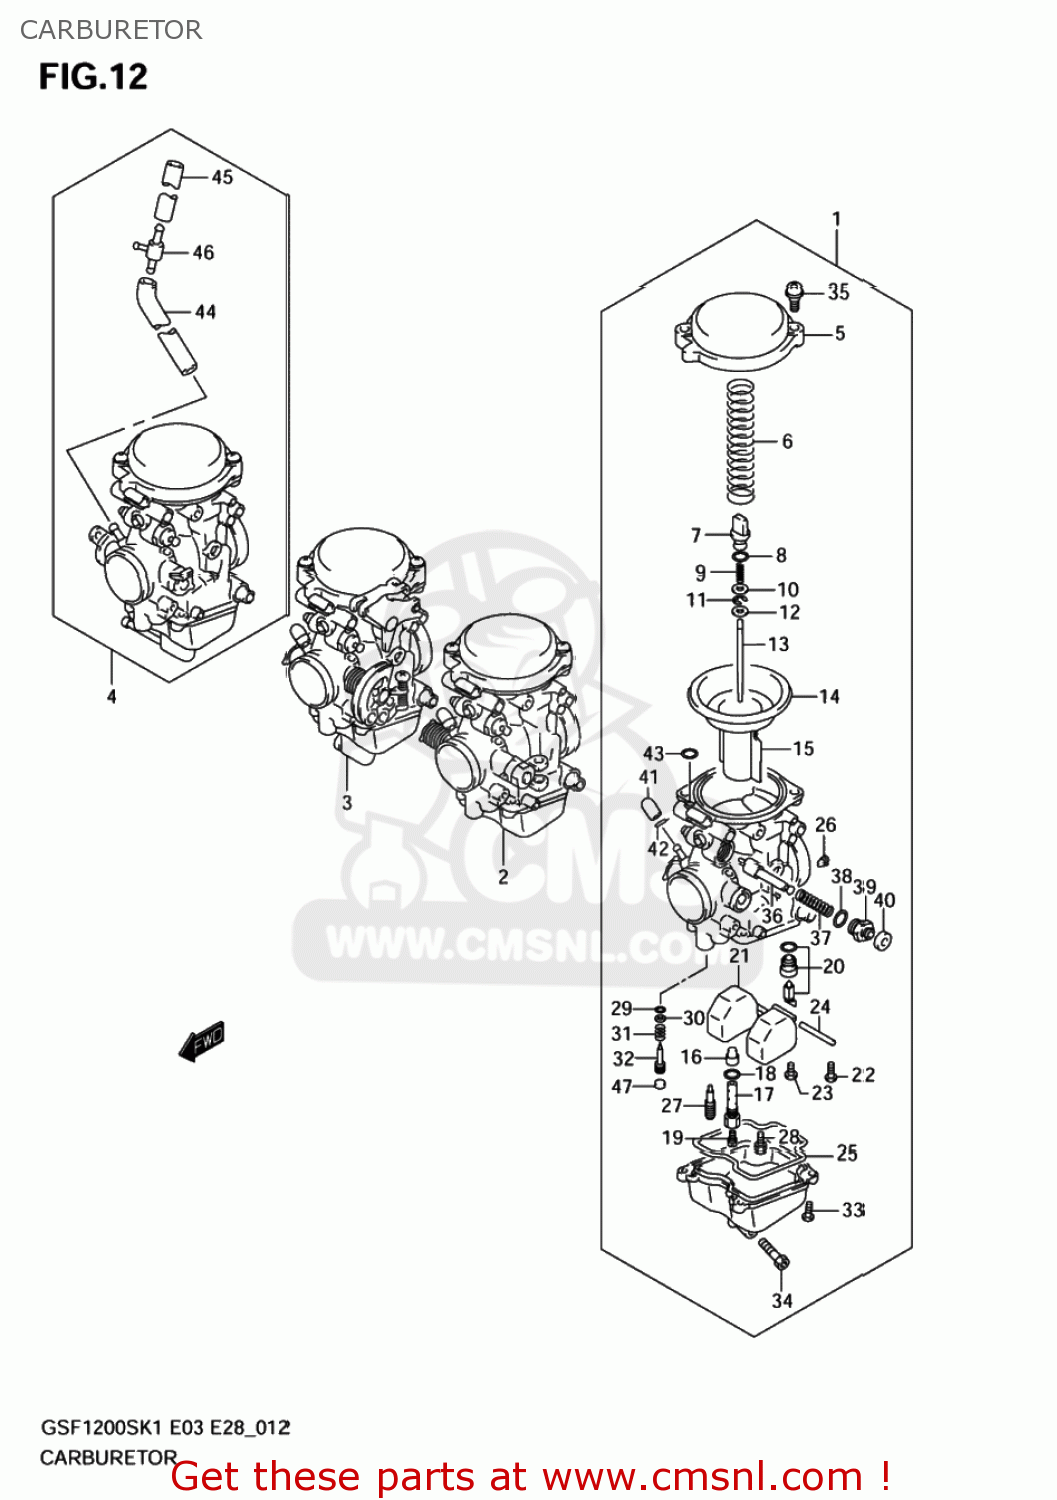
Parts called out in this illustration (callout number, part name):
1	CARBURETOR ASSY,L
2	CARBURETOR ASSY,ML
3	CARBURETOR ASSY,MR
4	CARBURETOR ASSY,R
5	COVER,DIAPHRAGM
6	SPRING
7	HOLDER
8	O RING(D:1.9,ID:4.8)
9	SPRING
10	WASHER
11	E RING,MULTIPLE JET NOZZLE
12	RING
13	NEEDLE,JET(5C71-1)
14	DIAPHRAGM
15	VALVE,PISTON
16	JET,NEEDLE(P-0M)
17	HOLDER,JET
18	O RING
19	JET,MAIN(100)
20	VALVE ASSY,NEEDLE
21	FLOAT ASSY
22	SCREW
23	SCREW
24	PIN,FLOAT
25	GASKET (NAS)
26	JET,PILOT AIR(1.7)
27	JET,PILOT(15)
28	JET,MAIN(60)
29	O RING,PILOT AIR SCREW
30	WASHER
31	SPRING,THROTTLE SCREW
32	ADJUSTER
33	SCREW
34	SCREW,DRAIN
35	SCREW
36	PLUNGER
37	SPRING
38	O RING
39	GUIDE SCREW,PLUNGER
40	CAP,STARTER VALVE
41	CAP
42	CLIP
43	O RING
44	HOSE(5X9X600)
45	HOSE
46	NIPPLE
47	PLUG
